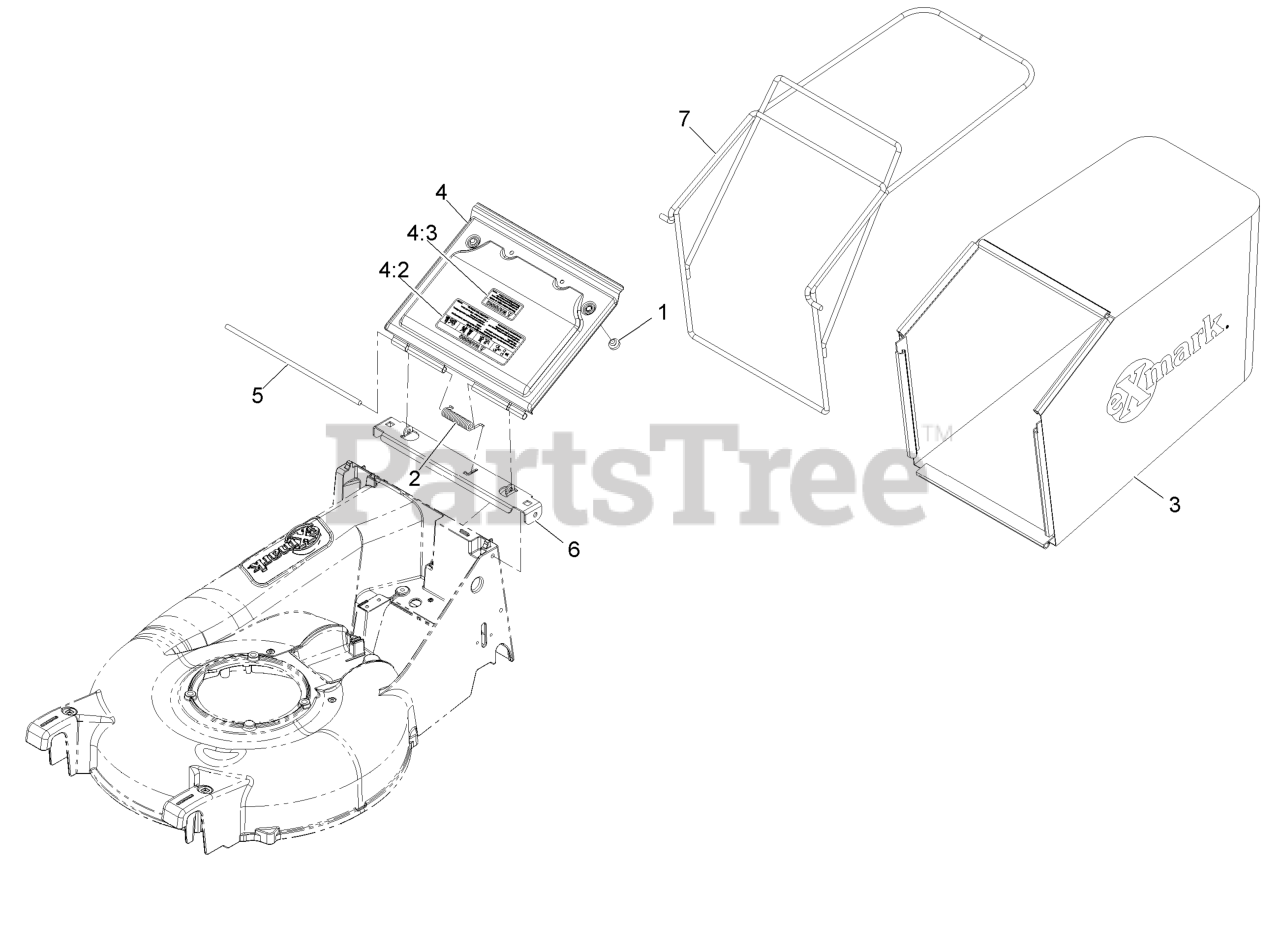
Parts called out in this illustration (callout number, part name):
2	SPRING-TORSION,COVER
3	BAG,GRASS P21
4	DOOR W/DECAL
4:2	DECAL-WARNING
4:3	DECAL-WARNING DOOR SM
5	ROD,DOOR PIVOT
6	BRACKET-DOOR P21
7	WLD,BAG FRAME
